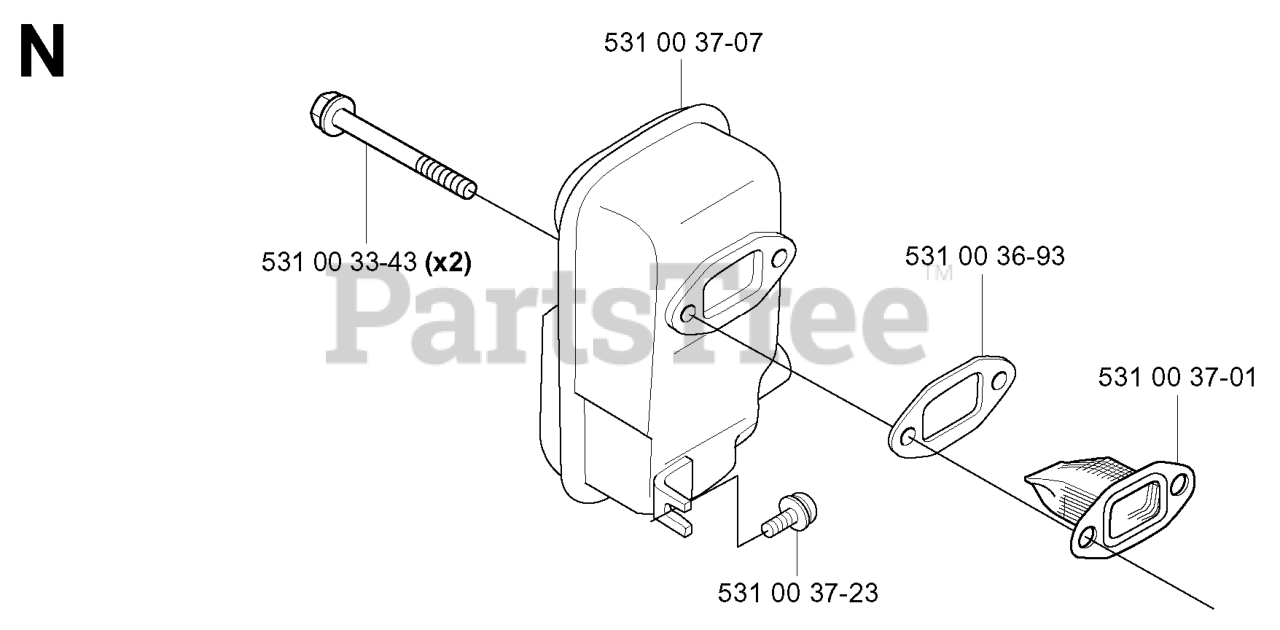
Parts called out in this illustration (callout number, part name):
1	LABEL
2	RP.DECAL.BADGE.170MM.TEXTLOGO
3	DECAL
6	DECAL 80 DBA
7	DECAL.INTERNATIONL.CUTFINGER
8	DECAL
9	DECAL BTRY SYMBOLS
10	DECAL PARK BRAKE
11	DECAL, DEFLECT WARNING
12	DECAL.V-BELT.SCHEMATIC.36/38/9
13	DECAL
